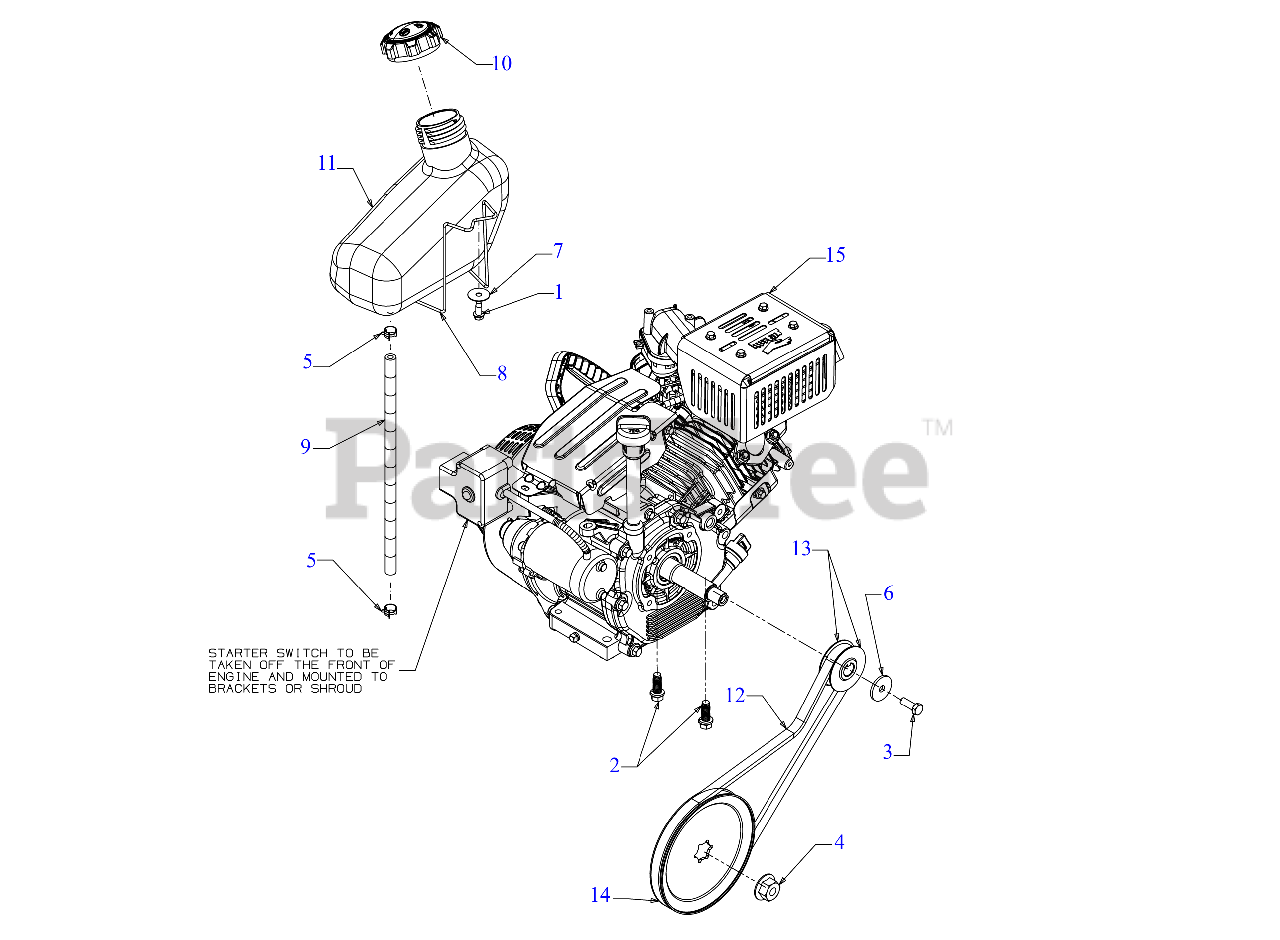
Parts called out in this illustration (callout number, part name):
1	SCREW 1/4-10:.625
2	SCREW 3/8-16 x 1
3	SCREW 5/16-24 x .875 GR5
4	FLANGE NUT W/HUB
5	HOSE CLAMP 1/20
6	WASHER-5/16 x 1.25X 1.27
7	FLAT WASHER
8	SUPPORT WIRE
9	FUEL HOSE LOW PERMEATION 13"
11	FUEL TANK (2 QT)
12	V-BELT .500 x 35.00LG
13	HALF PULLEY
14	AUGER PULLEY
15	COMPLETE ENGINE 208cc
